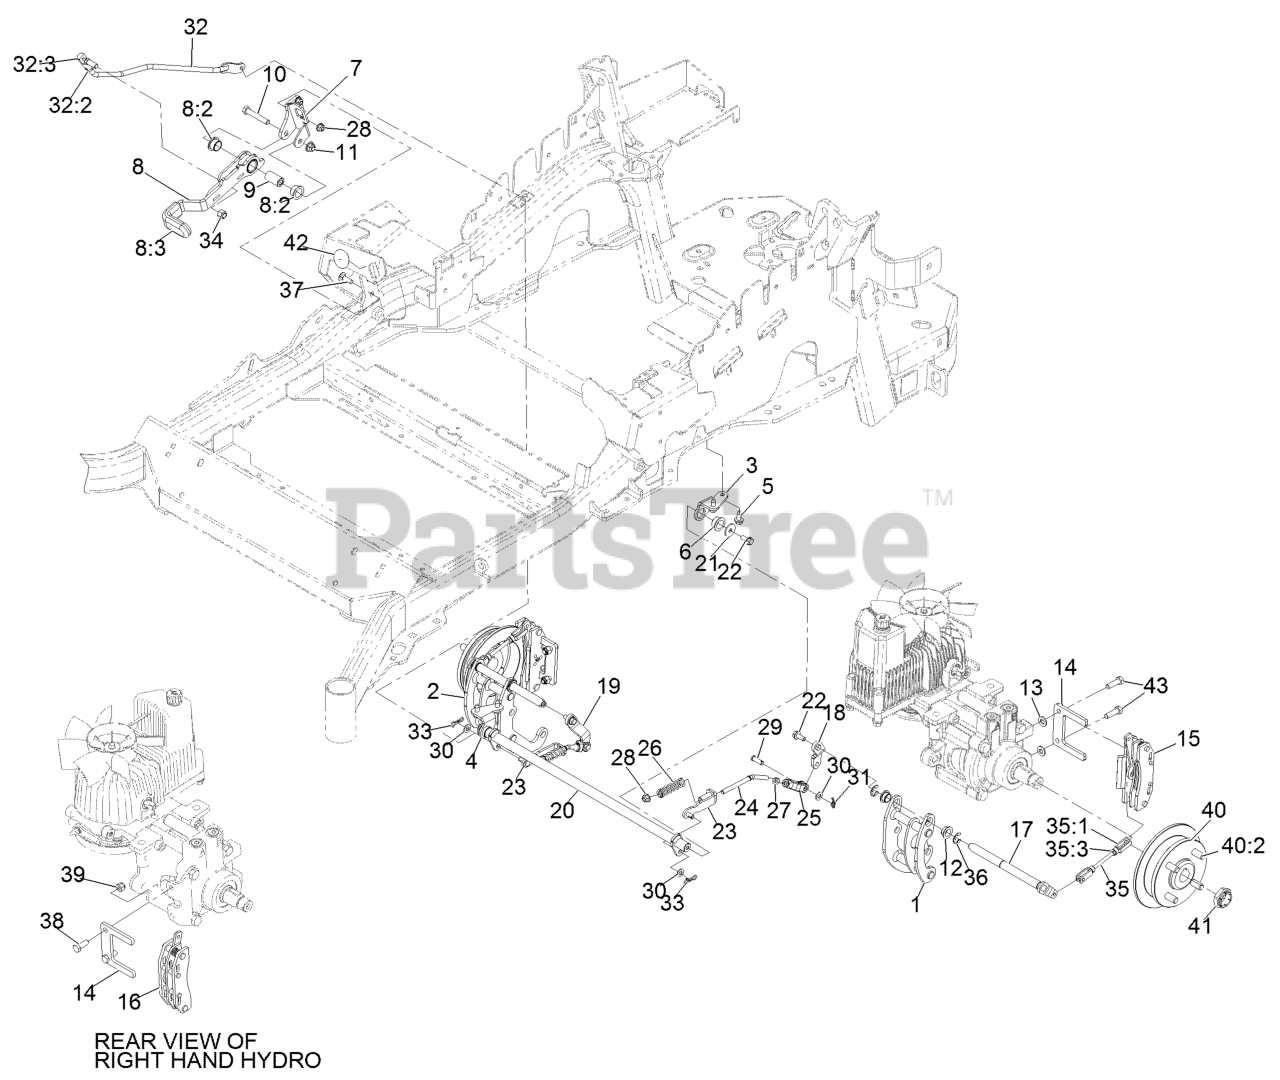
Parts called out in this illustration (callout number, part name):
3	MOUNT-PIVOT, LH
4	MOUNT-PIVOT, RH
5	Screw-HWH 5/16-18 X 3/4 Tf
6	BUSHING-FLANGE
7	BRACKET-MOUNT
8	BRAKE LEVER ASM
8:2	BUSHING-FLANGE
8:3	GRIP-LEVER
9	HANDLE-PIVOT, BRAKE
10	SCREW-HH
11	NUT-HF, NI
12	BUSHING
13	WASHER-FLAT
14	PLATE-MOUNT, BRAKE
15	CALIPER-BRAKE
16	CALIPER-BRAKE, RH
18	ARM-INNER, LH
19	ARM-INNER, RH
20	SHAFT-CROSS
21	WASHER-FLAT
22	SCREW-HHF
23	BRACKET-L
24	LINKAGE-MID
25	YOKE-OFFSET
26	SPRING-COMPRESSION
27	NUT-JAM
28	NUT-HF, NI
29	PIN-CLEVIS
30	WASHER-PLAIN
31	PIN-COTTER, LOCKING
32	FRONT LINKAGE ASM
32:2	END-TIE ROD, RH
32:3	NUT-HJ
33	PIN-COTTER, LOCKING
34	NUT-LOCK
35	REAR LINKAGE ASM
35:3	NUT-JAM
37	BOLT-CARR
38	SCREW-HH
39	NUT-LOCK, NI
40	WHEEL HUB ASM
40:2	STUD-WHEEL
41	LOCKNUT
42	DECAL-COVER
43	SCREW-LOCK, PATCH
